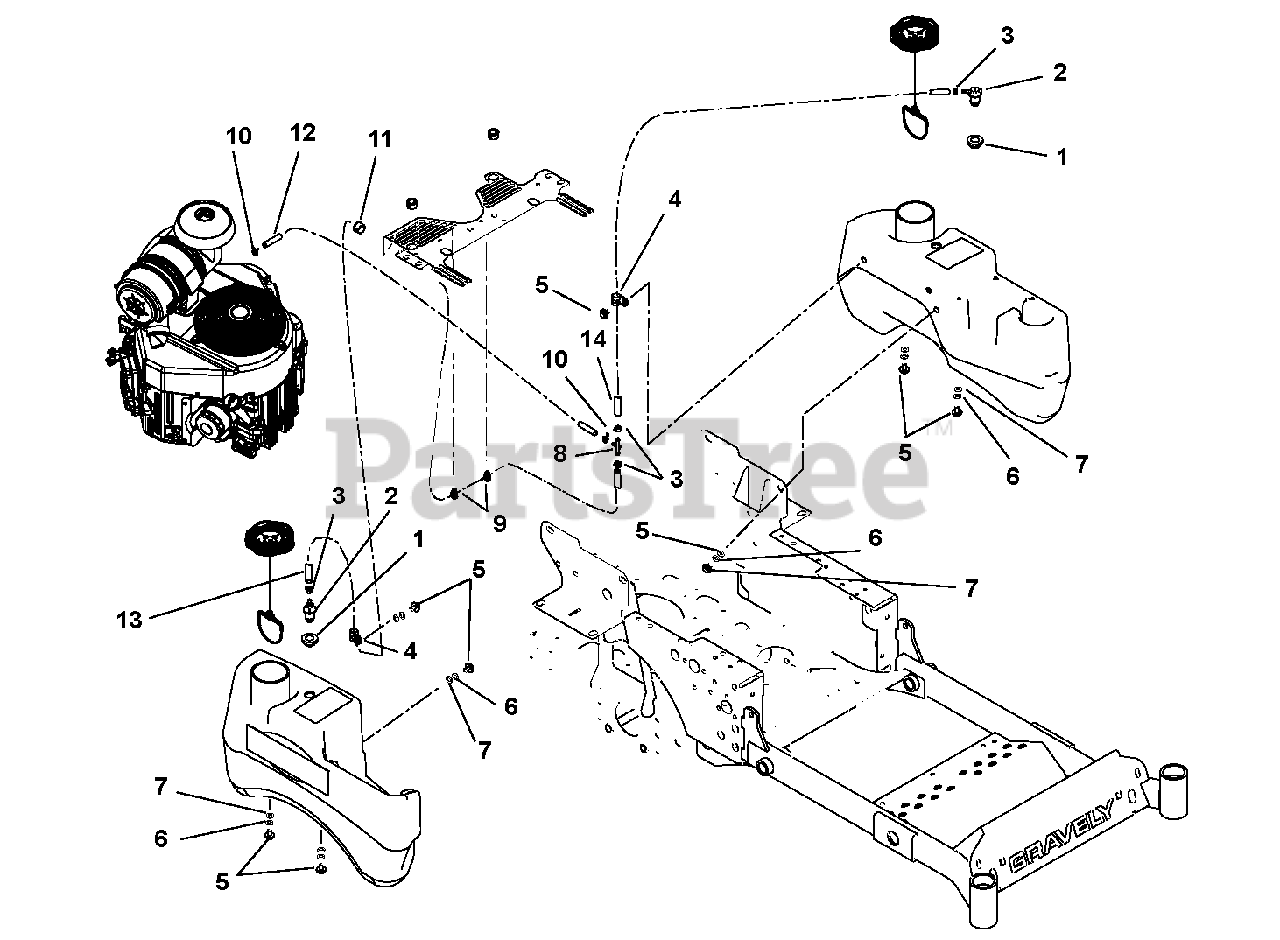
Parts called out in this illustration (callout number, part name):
2	Valve
3	Hose, Clamp
5	Bolt, .31-18 x .62
6	Washer, Locking .31 x .078 Regular
7	Washer, Flat Steel .38 x .875 x .083
8	Fitting, Tee 1/4 x 3/8
9	Clip, Routing
10	Clamp, Spring .188
11	Bushing, Snap
12	Hose, Fuel
13	Hose, Fuel
14	Hose, Fuel
